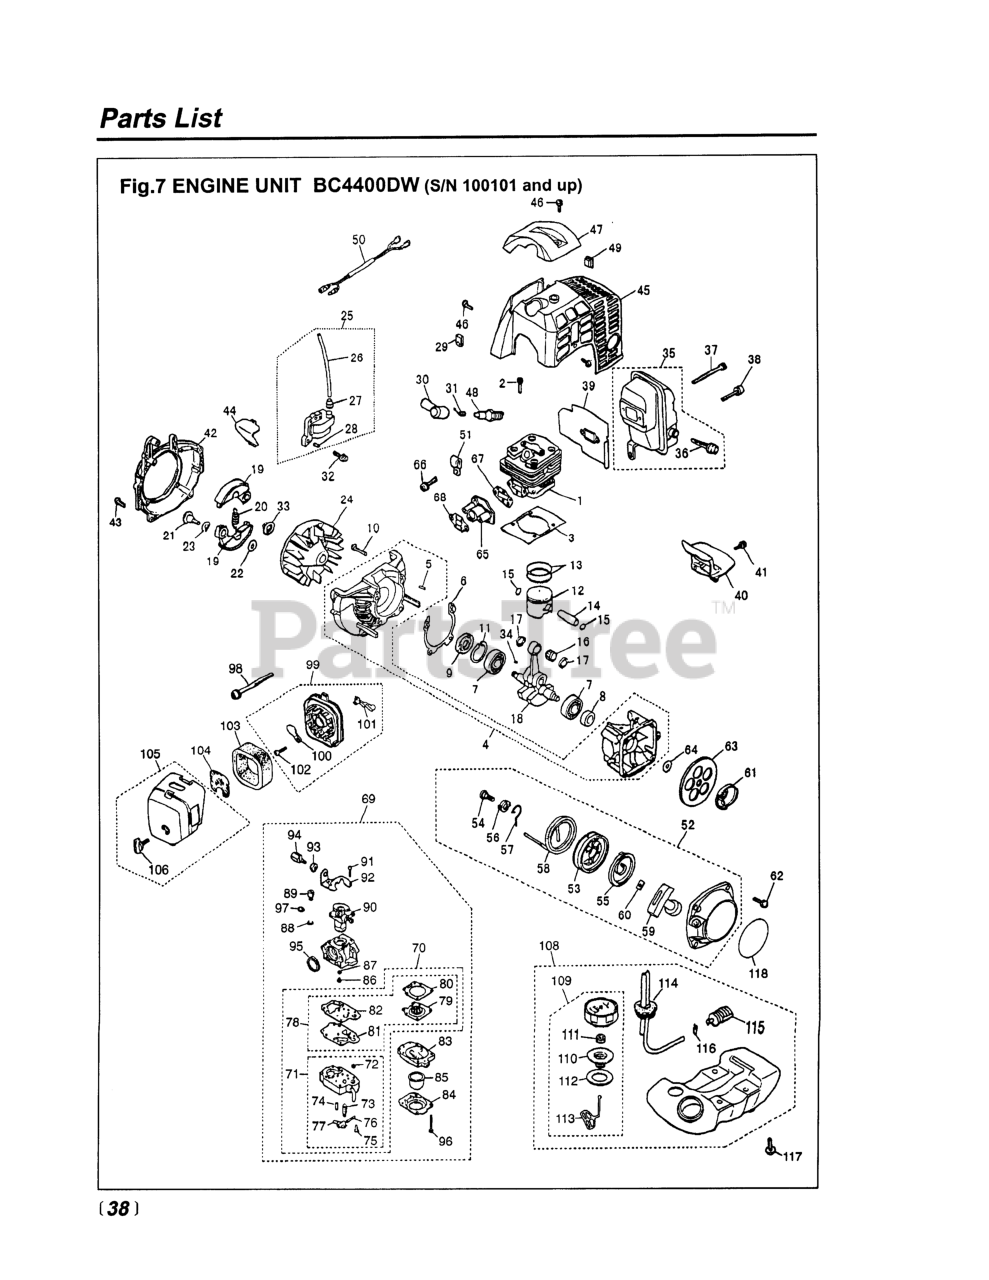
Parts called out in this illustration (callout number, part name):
1	CYLINDER
2	BOLT, M5 X 22
3	GASKET, BASE
4	CRANKCASE COMP (RPLS. -21100)
5	PIN
6	GASKET
8	SEAL
9	SEAL, OIL (RPLS 1200-21220)
10	BOLT, M5 X 30
11	RING, SNAP, M32 x 1.2
13	RING, PISTON (RPLS -41210)
14	PIN, PISTON
15	RING, SNAP
16	BEARING
17	WASHER
18	CRANKSHAFT COMPL
19	SHOE, CLUTCH (RPLS 4500-51110)
20	SPRING
21	SCREW
22	WASHER
23	WASHER (RPLS. -51240)
24	ROTOR
25	COIL ASSEMBLY
26	CORD (RPLS 4700- )
27	CAP
29	GROMMET
30	CAP
31	SPRING
32	BOLT, M4 x 22
34	KEY
35	MUFFLER ASSEMBLY
36	ARRESTER (RPLS 5850-15140)
37	BOLT, M5 x 65
38	BOLT (REPLACES 01252-30514)
39	GASKET, MUFFLER (RPLS -15210)
40	PLATE (RPLS-15220)
41	SCREW,M5 X 14 (RPLS 1400-15510
42	COVER
43	BOLT M5 x 20 (RPLS -12280)
45	COVER
46	SCREW M5 x 12
47	GUARD
50	CORD COMPLETE
51	CLAMP
52	RECOIL ASSEMBLY
53	REEL
54	SCREW
55	SPRING, SPIRAL
56	COLLAR
57	ARM
58	ROPE (USE 4810-75160)
59	KNOB
60	PLATE, STOPPER
61	PULLEY
62	SCREW, M6 x 14
65	INSULATOR (REPLACES -13160)
66	SCREW
67	GASKET, INSULATOR
68	GASKET, CARBURETOR
69	CARBURETOR ASSEMBLY
71	BODY, PUMP
72	SCREEN
73	VALVE, INLET
75	SCREW
76	PIN
77	LEVER
79	DIAPHRAGM
80	GASKET, DIAPHRAGM
81	DIAPHRAGM, PUMP
82	GASKET, PUMP
83	BODY, PURGE
84	COVER, PUMP
85	PUMP, PRIMING
87	RING, O
88	RING
89	SWIVEL
90	VALVE ASSY
91	SCREW
93	NUT, CABLE ADJUSTER
94	SCREW, CABLE ADJUSTER
95	RING, PACKING
96	SCREW
97	WASHER
98	SCREW (RPLS 0263-30550)
99	BODY ASSEMBLY
100	PLATE, CHOKE
101	LEVER, CHOKE
102	SCREW (REPLACES 50030272)
103	ELEMENT
104	SCREEN
106	KNOB (RPLS -82220)
109	CAP ASSY (RPLS -85201)
110	HOLDER (REPLACES -85230)
111	FILTER
112	PACKING
113	STOPPER
114	PIPE COMP.
115	FILTER ASSY
116	CLIP (REPLACES 2841-31280)
117	SCREW, M5 X 22
